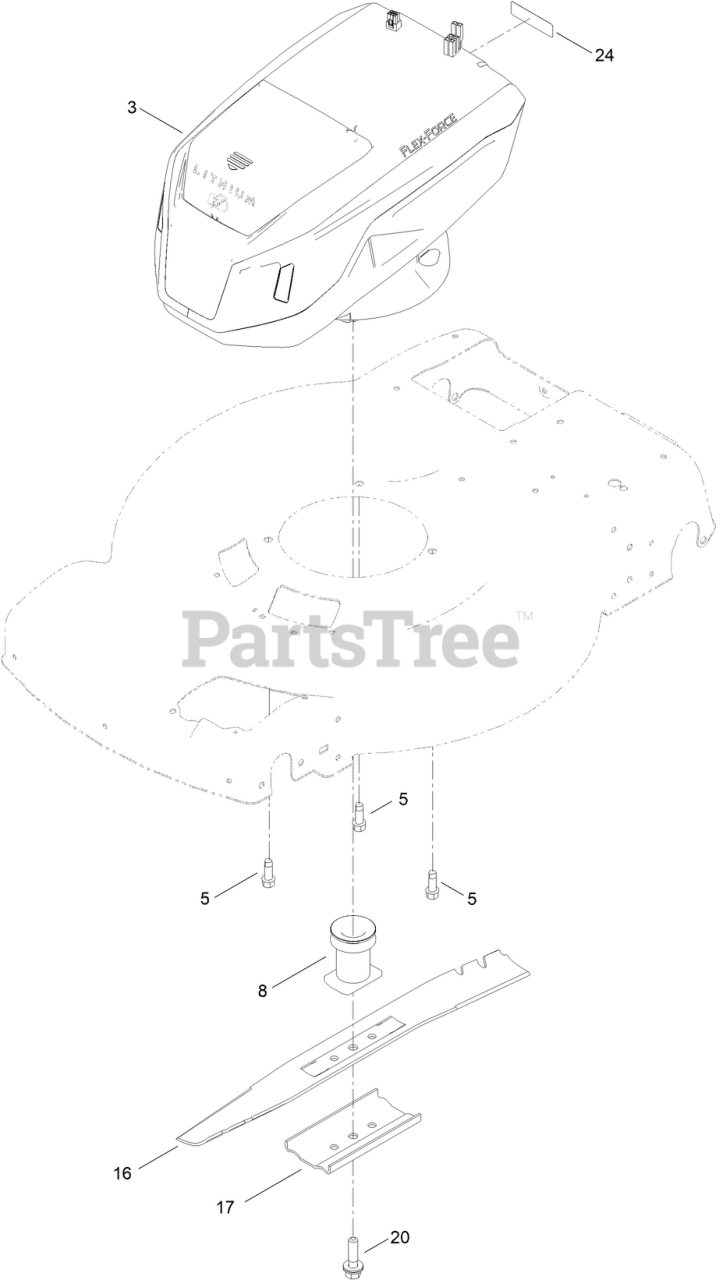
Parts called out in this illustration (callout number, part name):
3	MOTOR MODULE 60V
5	SCREW-THD FORM, HWH
8	DRIVER-BLADE
16	BLADE [BLACK]
17	SUPPORT-BLADE
20	BOLT-BLADE
24	DECAL-PROP 65, SHORT, TRILINGUAL
